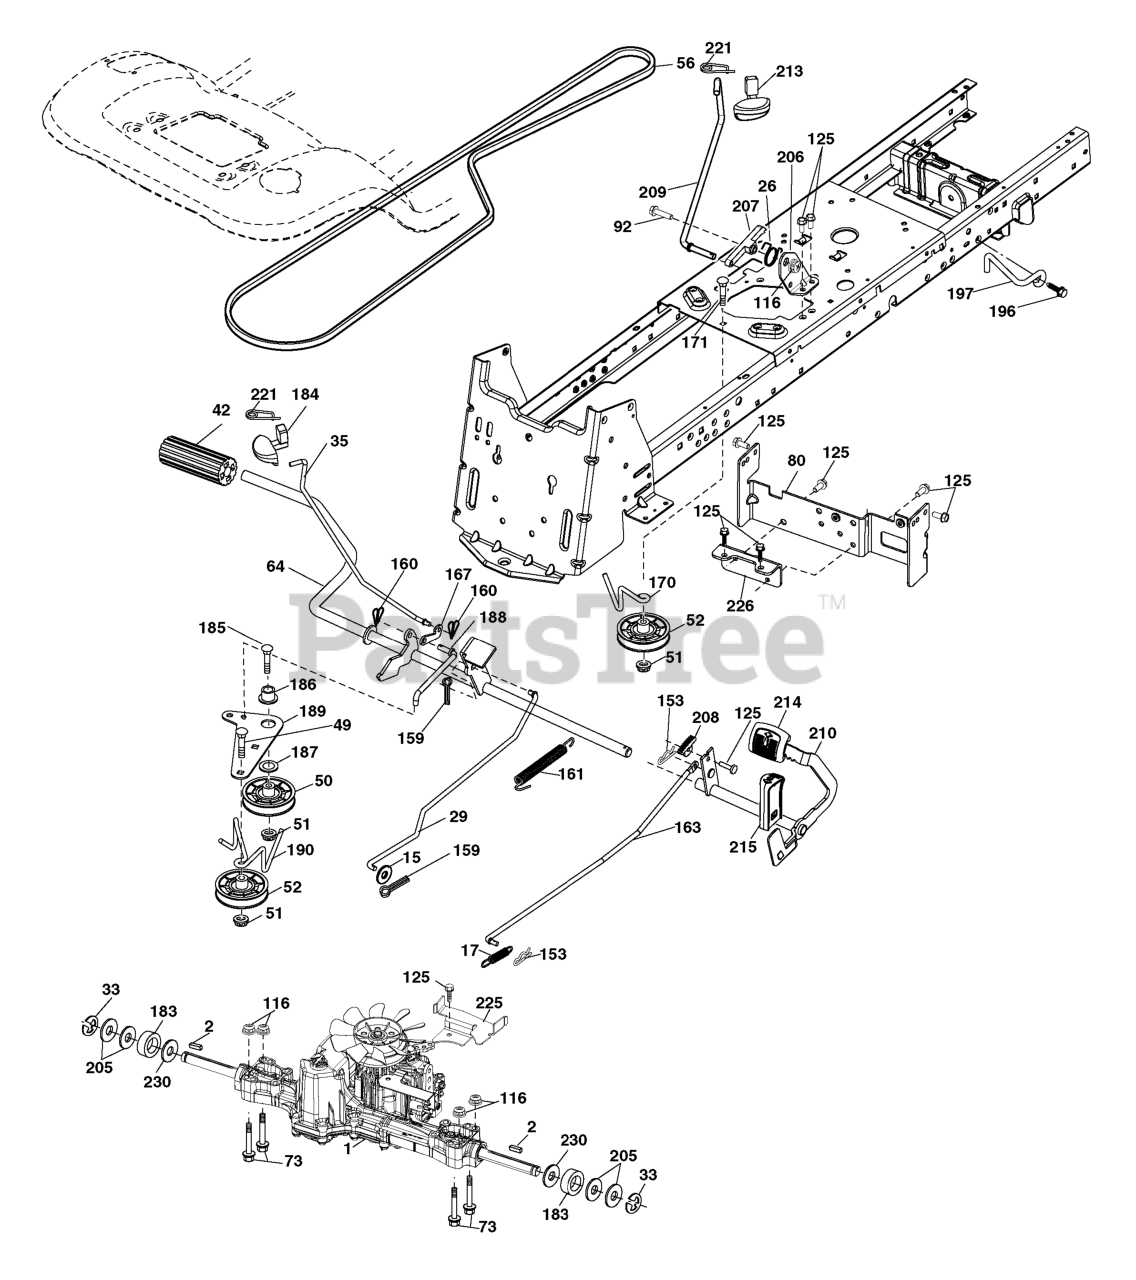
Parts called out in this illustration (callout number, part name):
1	TRANSAXLE, TUFFTORQ K46
2	SQUARE KEY
15	WASHER
17	SPRING.BRAKE.K46
26	SPRING.RETURN.CRUISE
29	ROD.BRAKE.K46
35	ROD.BRAKE.PARKING.GT.H
42	PEDAL COVER T
50	IDLER.FLAT.910.OFFSET
51	NUT LOCK FLG 3/8-16 UNC
52	IDLER.V-GROOVE.910.OFFSET
56	V-BELT.MOWER.92.40.42/K46
64	SHAFT.ASM.PEDAL.BRK.CNTR
73	BOLT HEX 5/16-18 GR 5
80	STRAP.TORQUE.HG3000/K46
92	BOLT
116	NUT LOCK HEX FLANGE 5/16-18
125	SCREW
153	RETAINER M
159	COTTER PIN
160	RETAINER CLIP
161	SPRING.RETURN.CLUTCH.2006
163	ROD.CONTROL.PEDAL.K46
167	LATCH.BRAKE.SPRING
170	KEEPER.V-IDLER.CENTER.
171	BOLT
183	SPACER AXLE
184	HANDLE.PARKG.BRK.HUSQ X667
185	BOLT
186	SPACER.RETAINER
187	WASHER 12/32X2X10GA
188	RP.LINK.CLUTCH.GROUND.DRIVE
189	BELLCRANK.GROUND.DRIVE.TEX.
190	KEEPER.BELLCRANK.DRIVE
196	SCREW 3/8-16X1
197	LINK.CLUTCH.ANIT-ROTAT
206	BRKT.MOUNT.LATCH.CRUIS
207	LATCH.CONTROL.CRUISE
208	GEAR.SECTOR.CONTROL.CR
209	ROD.CONTROL.CRUISE.GT.
210	ROCKER.ASM.PEDAL.CONTR
213	KNOB.CONTROL.CRUSIE.HU
214	PEDAL.FORWARD.TEX.GT.4
215	PEDAL.REVERSE.TEX.GT.4
221	RETAINER.SPRING.CLIP.H
225	KEEPER.BELT.TRANSAXLE.K46
226	BRACKET.MOUNT.TORQUE.K46.TLT
230	WASHER.HARDENED
